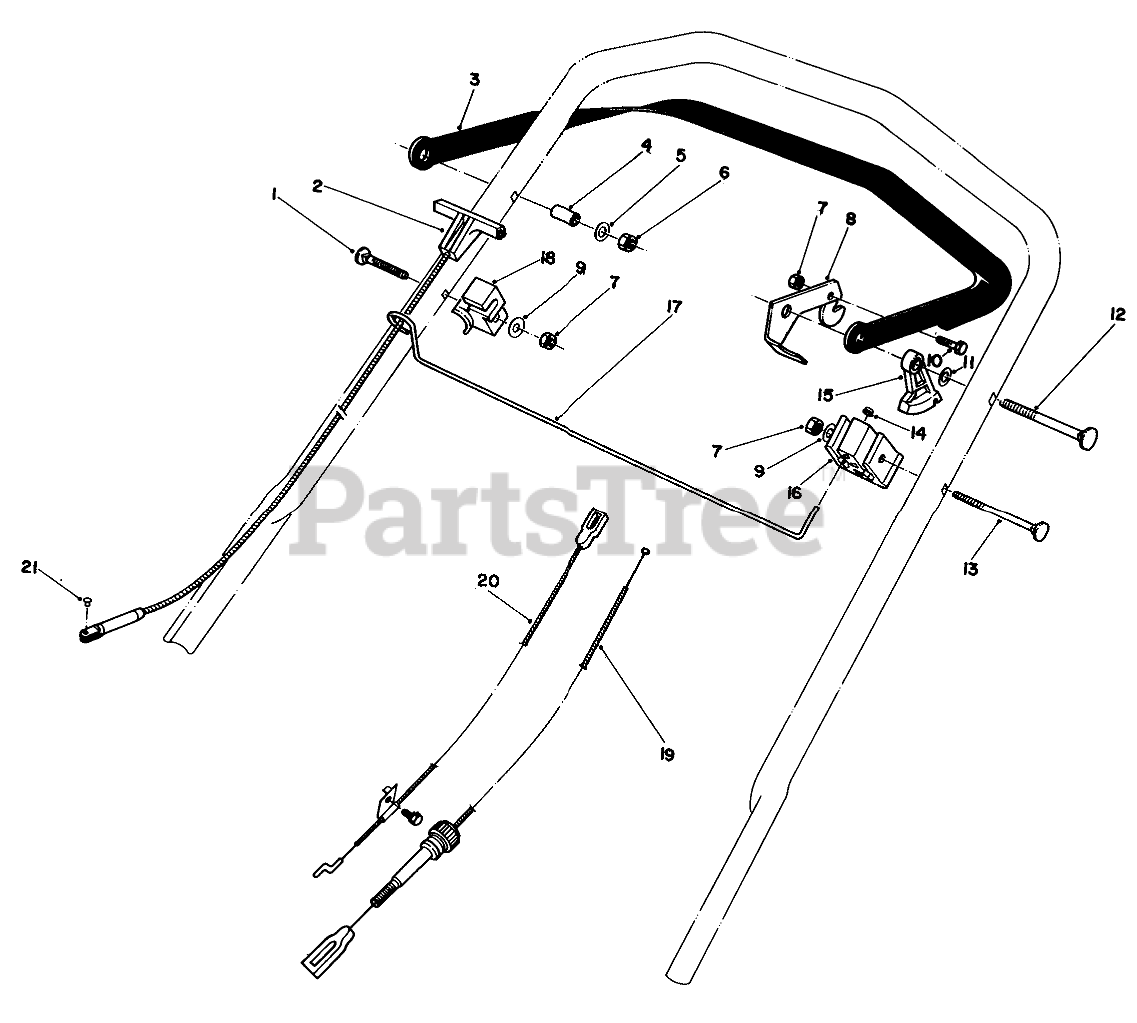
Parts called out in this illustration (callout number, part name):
1	SCREW-HANDLE
2	Rope-Starter
3	Bar-Control
4	Spacer
5	WASHER-PLAIN
6	NUT-LOCK, NI
7	NUT-LOCK, NI
8	Lever-Control
9	WASHER-FLAT
10	SCREW-HH
11	WASHER-FLAT
12	5/16-18 X 2 HNDLE SCREW
13	SCREW-HANDLE
14	NUT-SPEED
15	LEVER-TRACTION
16	SUPPORT-CABLE
17	ROPE ROD PLATED
18	ROD CATCH
19	CABLE-TRACTION
20	BRAKE CABLE
